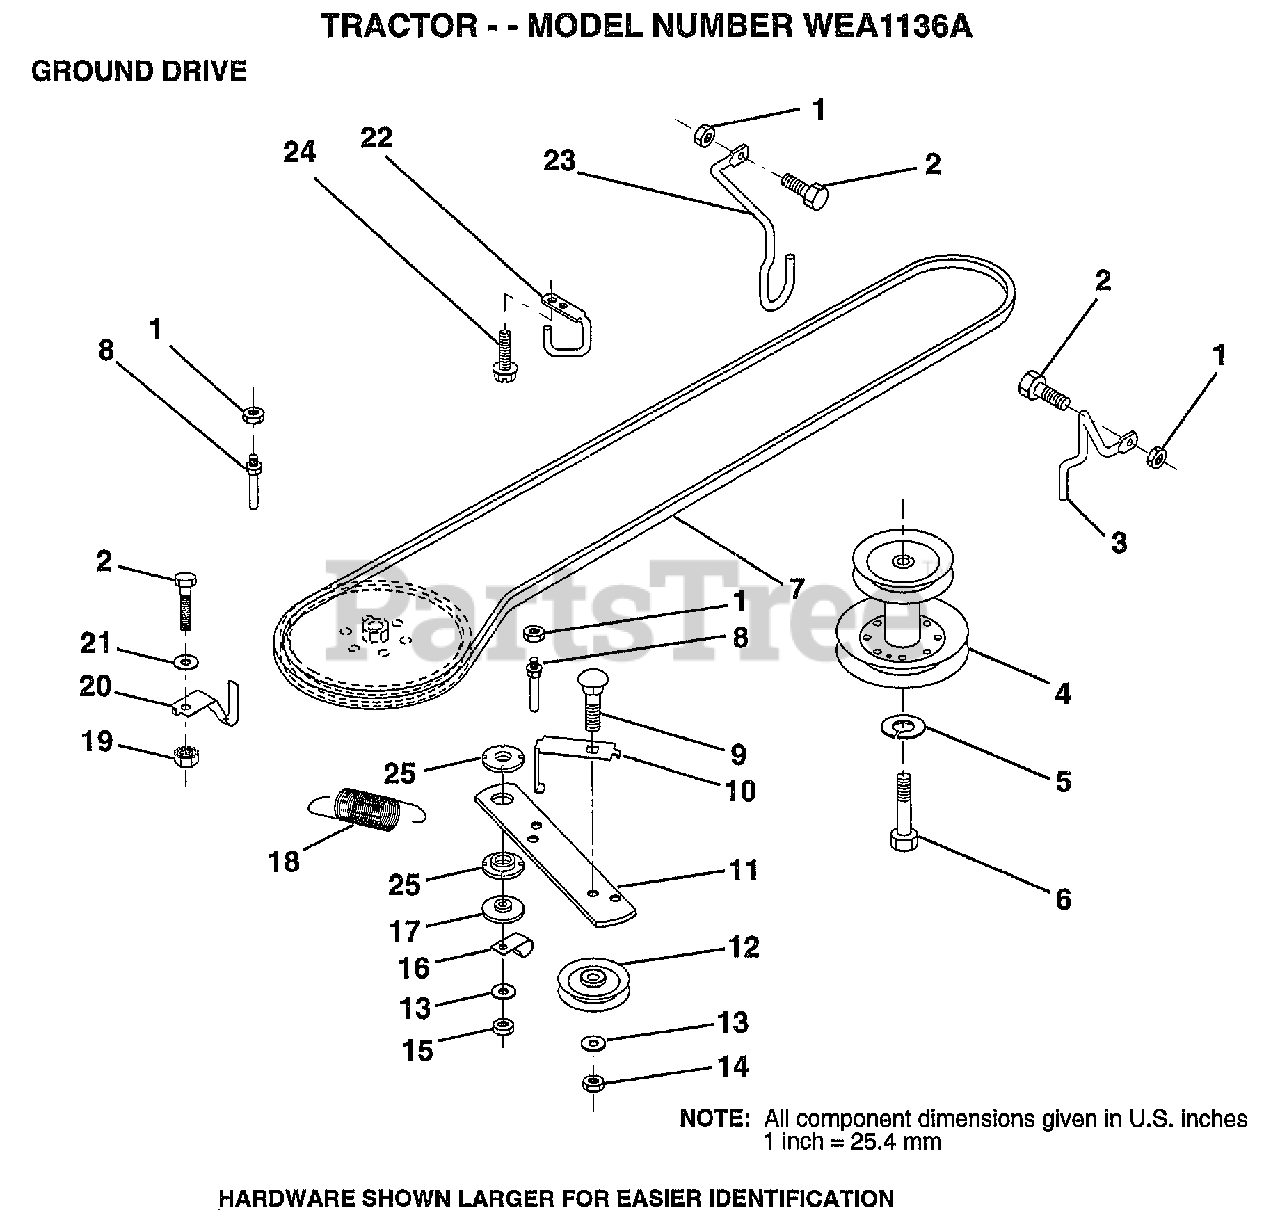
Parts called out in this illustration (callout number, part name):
2	BOLT
3	KEEPER RH
4	PULLEY.ENGINE.LR
5	LOCKWASHER
6	HEX BOLT
7	V BELT
8	"KEEPER,DRIVE BELT"
9	BOLT
10	"KEEP,IDLER DR BEL"
11	ARM-IDLER.DR.GRND
12	PULLEY.IDLER.FLAT
13	WASHER
14	LOCKNUT
16	"CLIP,INSULATOR"
17	SPACER
20	KEEPER.BELT.T/A
21	WASHER
22	"KEEPER,FRA DR BEL"
23	KEEPER MOWER LH
24	SCREW
25	BUSHING.NYLON
